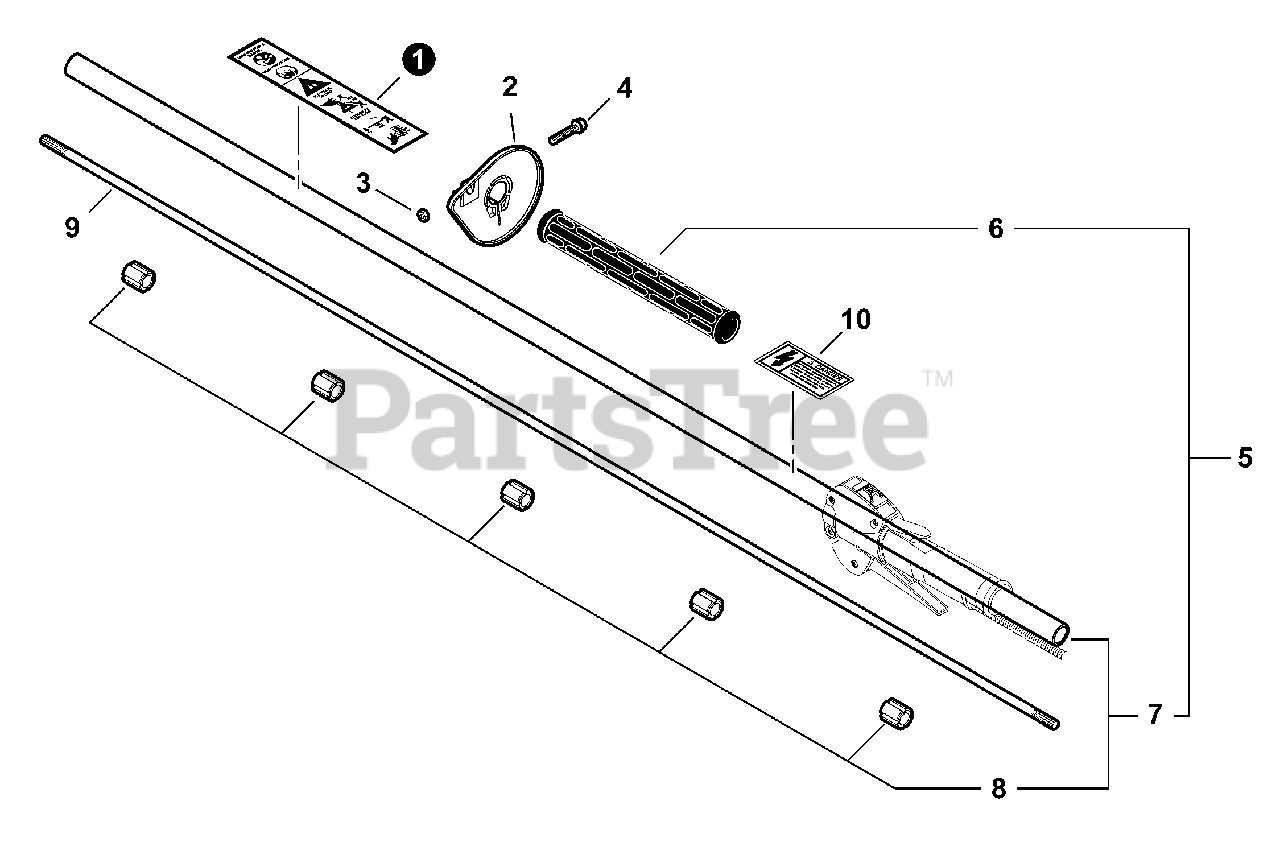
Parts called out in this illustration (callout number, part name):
1	LABEL, CAUTION
2	GUARD, HAND
4	SCREW M5×30
5	MAIN PIPE ASSY WITH GRIP
6	GRIP, FRONT
7	MAIN PIPE ASSY
8	BUSHING
9	MAINSHAFT
10	LABEL, HIGH VOLTAGE
